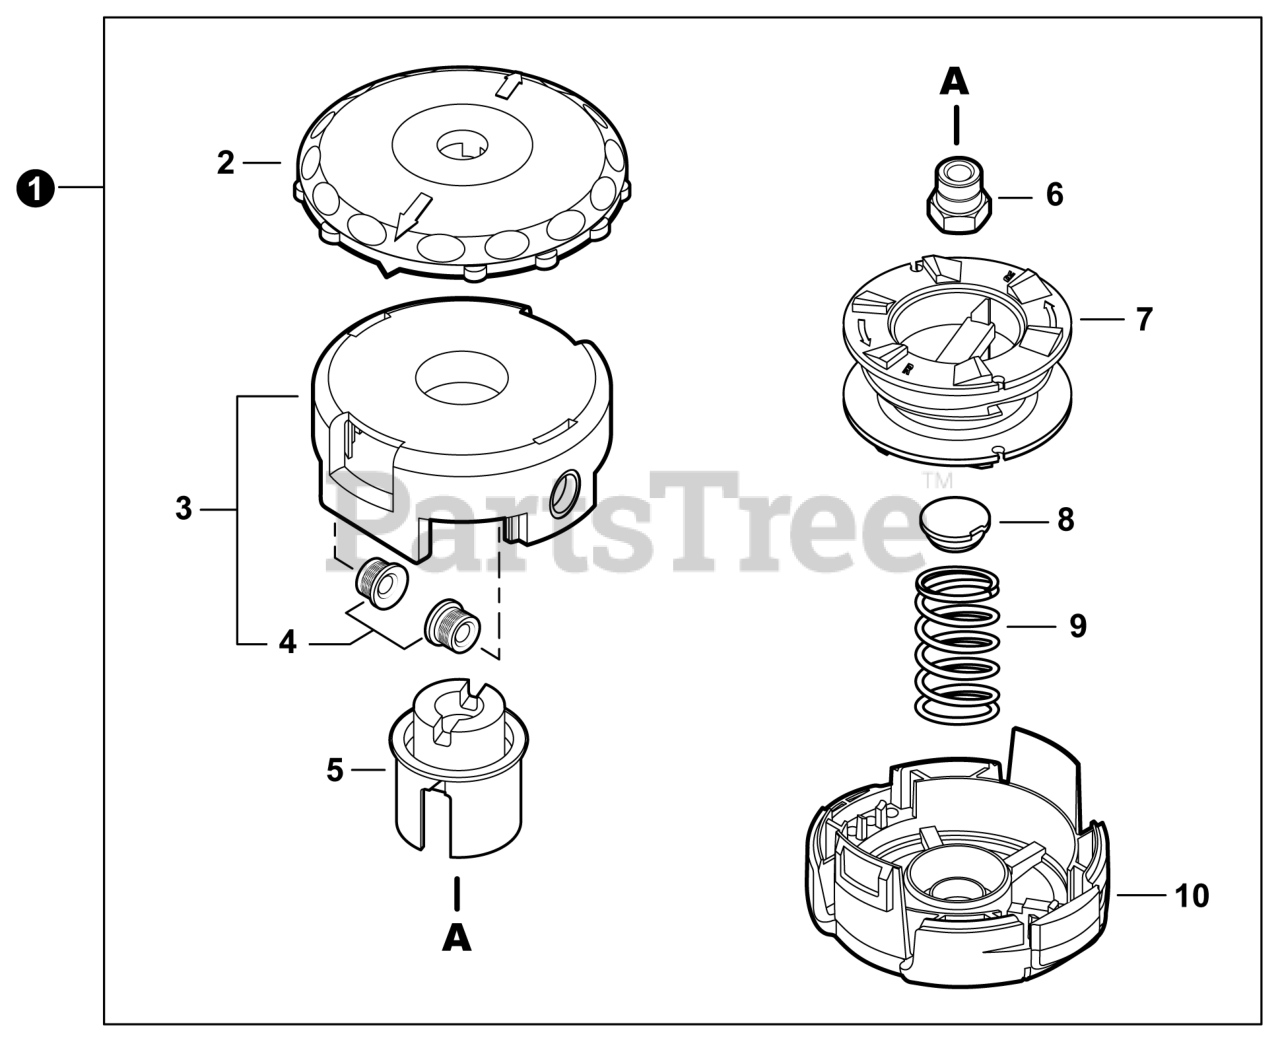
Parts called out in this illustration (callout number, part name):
1	TRIMMER HEAD, SPEED-FEED® 400
3	HOUSING ASSY, SPOOL
5	HUB (LH) BLACK
6	BUSHING M10x1.25 LH GOLD
8	CAP, SPRING
9	SPRING, GOLD
10	COVER, SPOOL
